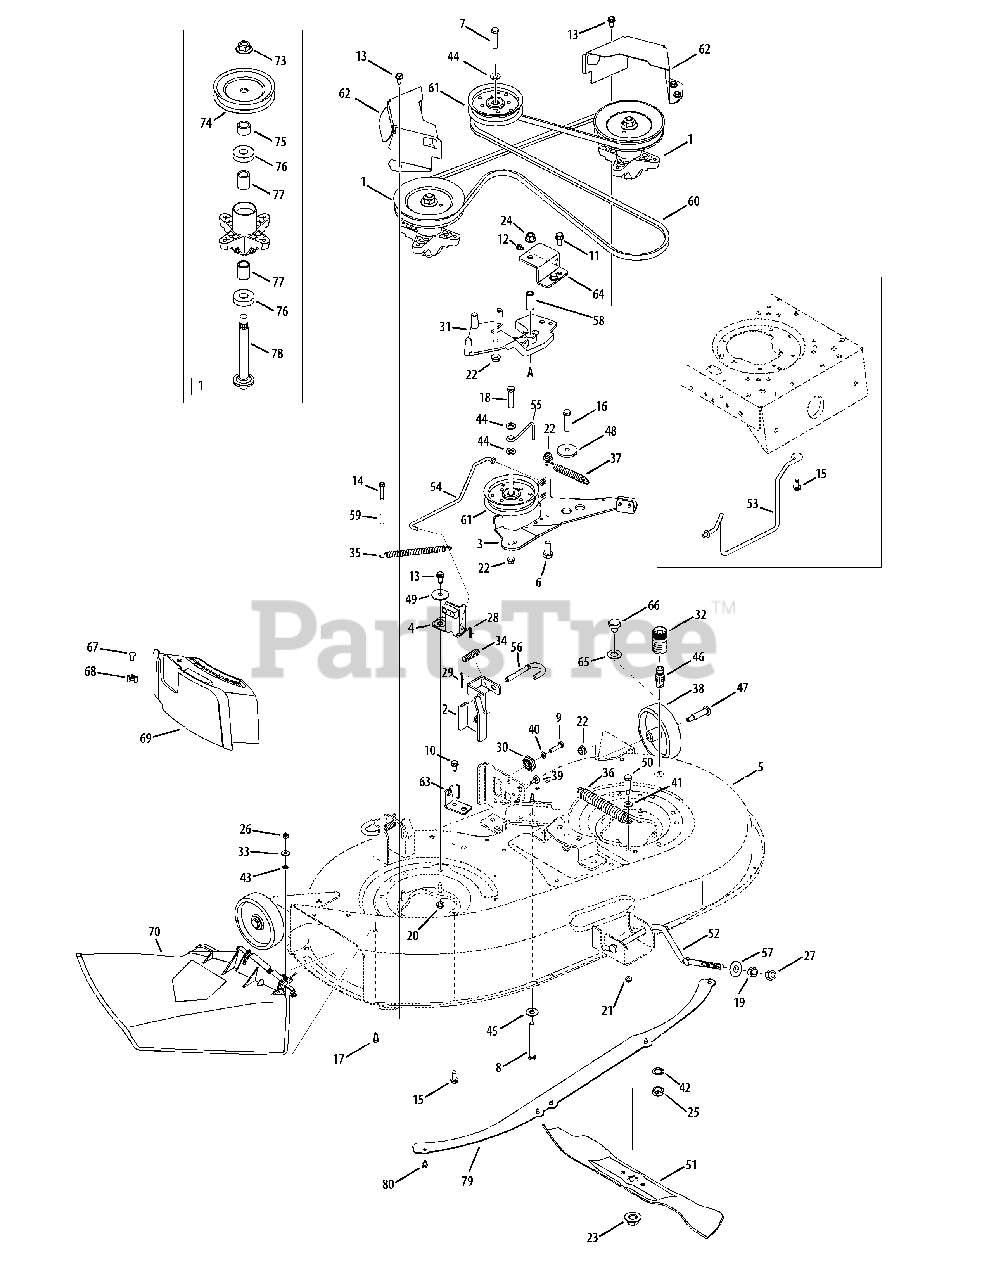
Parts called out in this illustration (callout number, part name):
1	Spindle Ass’y Pulley 6.3 Dia.
2	Deck Adjustment Bracket w/Weld Nut
3	Brake Assembly 42" Deck
4	Deck Brake Assembly
5	Deck Ass’y 42" w/wh. brkt
6	Hex Cap Screw 3/8-16 x .75
6	Hex Cap Screw 3/8-16 x 1.0
7	Hex Screw 3/8-16 x 1.75
8	Hex Screw 1/4-20 X 2.00
9	Hex Bolt 5/16-18 x 1.25
10	S-Tapp Scr 5/16-18 x .75
11	Hex S-Tapp Scr 3/8-24 X .50
12	Hex Wash HD Tapp Scr 1/4-20 x .375
13	Hex Hd. Cap Scr. 5/16-18 x .75
14	Hex Wash HD Bolt 1/4-20 x 1.50" Lg.
15	Hex Wash. Hd. Scr. 5/16-18 x .75 Lg.
16	Hex Bolt 3/8-16 x 1.25
17	Hex Cap Bolt 1/4-20 x .75" Lg.
18	Hex Bolt 3/8-16 x 2.0" Lg. (Gr. 5)
19	Hex Nut 1/2-13
20	Flange Locknut 5/16-18 Gr. F, Nylon
21	Hex L-Flanged Nut 1/4-20 Gr. F Nylon
22	Flange Lock-Nut 3/8-16 Gr. F Nylon
23	Hex Flange Nut 5/8-18
24	Flange Lock Nut, 7/16-20
25	Hex Nut M16-1.5 DIN 936
26	Hex Nut 1/4-20 Gr. 5
27	Hex Nut, 1/2-13
28	Int. Cotter Pin .072 x 1.13" Lg.
29	Cotter Pin 1/8" Dia x 1.25
30	Deck Adjustment Gear
32	Water Nozzle Adaptor
33	Bolt Retainer 1/4" x .50" OD
34	Compression Spring .531 OD x 1.75 Lg.
35	Extension Spring .50 dia x 6.37
35	Extension Spring .94 x 7.57
36	Extension Spring .94 x 6.74
37	Ext. Spring 4.74" Lg.
38	Wheel Ass’y - Deck 5" x 1.38"
40	L-Wash 5/16 ID
41	Flat Washer .28 ID x .74 DE x .063
42	L-Washer Internal
43	Cupped Washer .265 ID x .75 OD x .062
44	Flat Washer .385 ID x .87 OD x .06
45	Flat Washer .450 x 1.25 x .164
47	Shoulder Bolt .498 Dia x 1.53 x 3/8-16
48	Shoulder Spacer .884 x .190
49	Shoulder Spacer .50 x .1475
50	Shoulder Screw .374 x 1.16
51	3 in 1 Blade 21.23" Lg.
52	Adjustable Front Deck Rod
53	Belt Keeper Rod 42" Deck
54	Brake Control Rod 42"
55	Belt Keeper Rod, 42" Idler
56	Deck Release Pin
57	Deck Lift Pivot Cup
58	Spacer .455 x .697 x 1.585
59	Spacer .260 x .375 x 1.030 Lg.
61	Idler Pulley w/Flange 4.25 Dia
62	Belt Covers 6.0 dia.
63	Cable Deck Engage Bracket
65	Flat Washer .640 ID x 1.24 OD x .06
66	Screw Plug M16 x 1.50
67	Carriage Bolt 1/4-20 x .62
68	Wing Nut 1/4-20 Thd.
69	Mulching Plug
70	Chute Deflector (Plastic)
73	Hex Flange Nut 5/8-18
74	Deck Pulley 6.3 Dia.
75	Spacer .820 x 1.150 x .480
76	Ball Bearing 20 x 47 x 14:6204:DS
77	Spacer .080 x 1.10 x 1.322" Lg.
78	Spindle Shaft 5.50" lg.
79	Deck Skirt 42"
80	Hex Wash S-Tapp Scr 1/4-20 x .50
